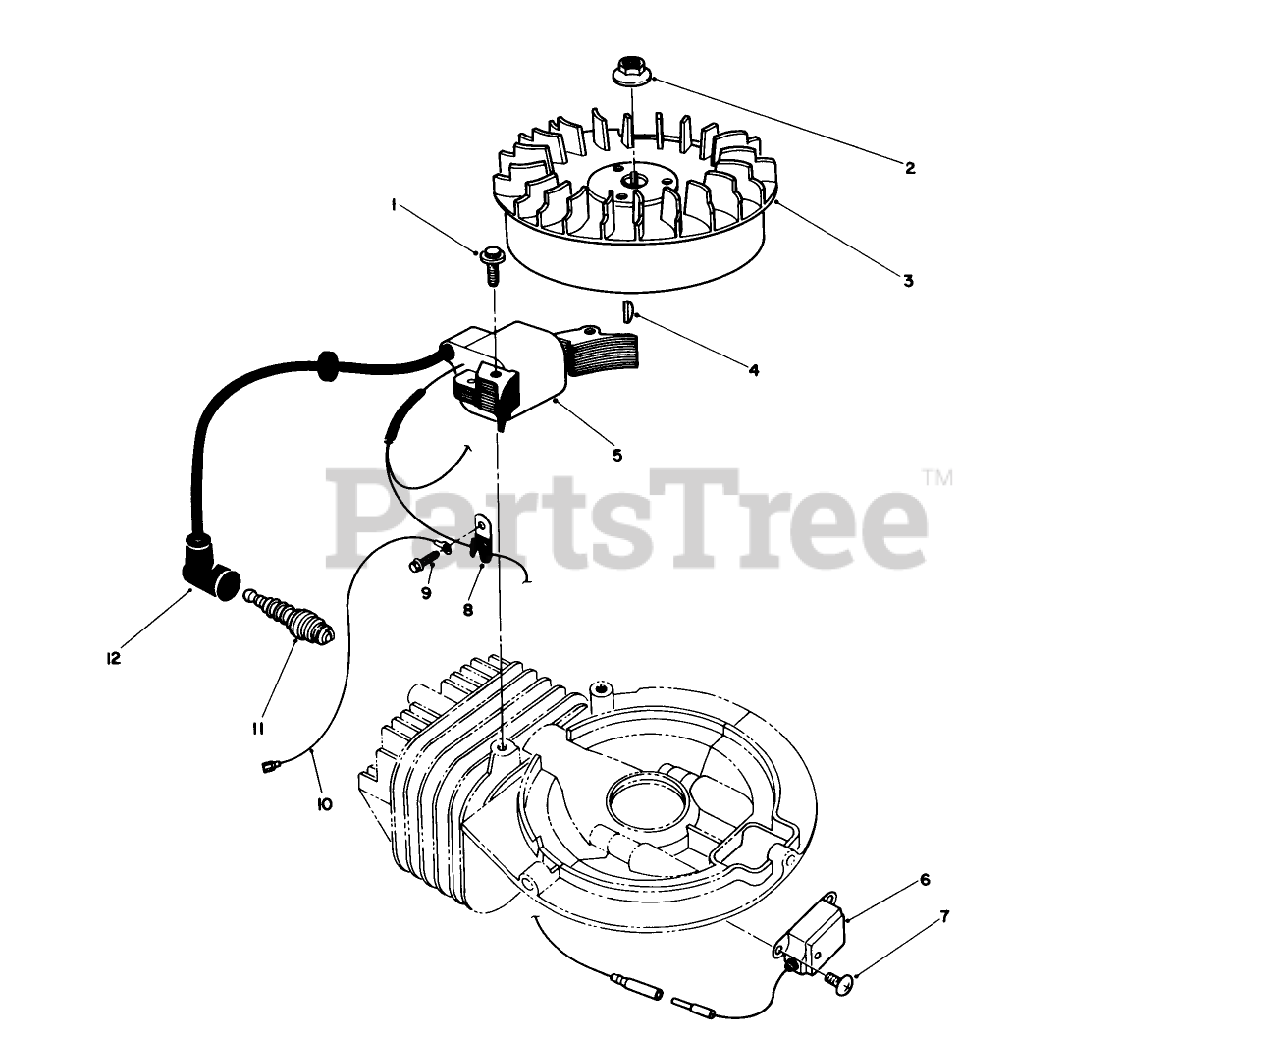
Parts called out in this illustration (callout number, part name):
1	SCREW
3	FLYWHEEL
5	MAGNETO COIL
6	MAGNETO MODULE
7	SCREW
8	CLAMP
12	CAP-SPARKPLUG
